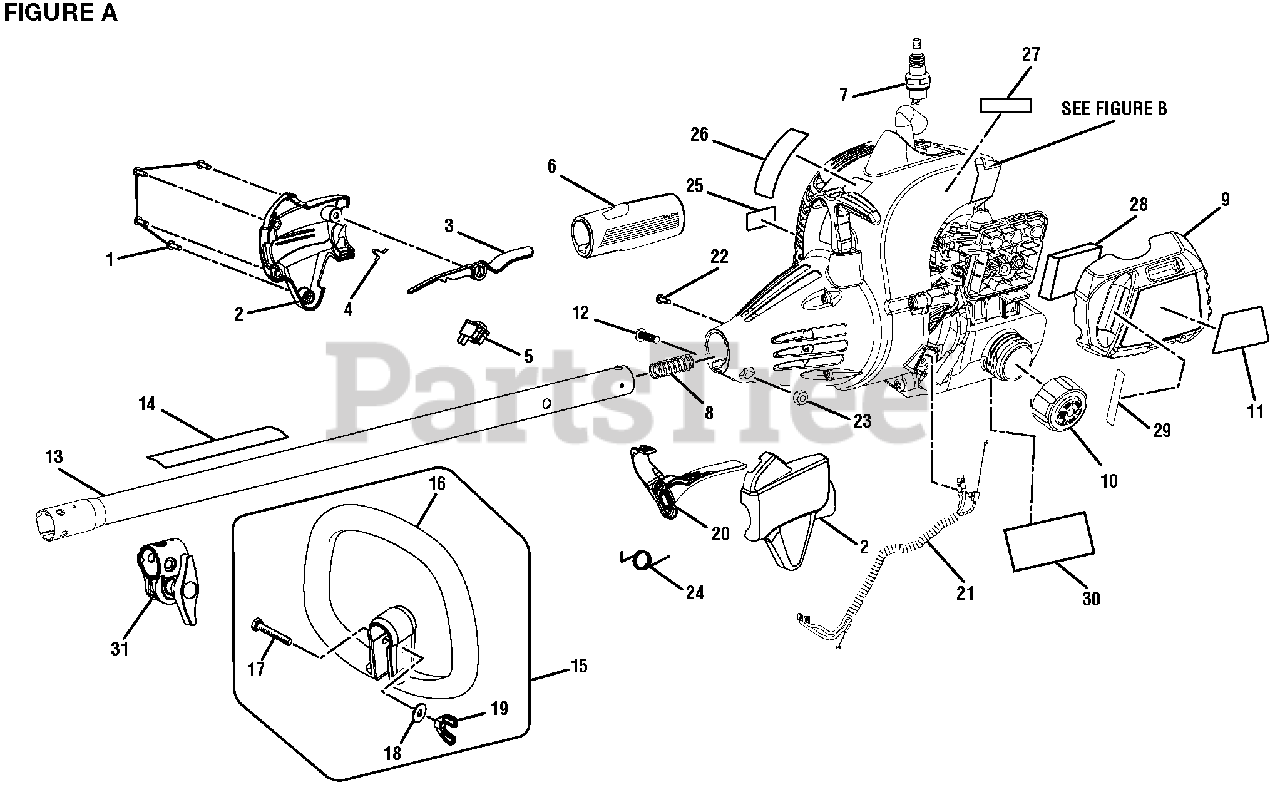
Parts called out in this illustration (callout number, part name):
1	Screw (M4 x 20 mm)
2	Control Handle Assembly
3	Trigger Lock
4	Strap Hanger
5	Switch (Momentary Contact)
6	Rear Handle
7	Spark Plug (Champion RCJ6Y)
8	Compression Spring
9	Air Box Cover
10	Fuel Cap Assembly (1.5 in. Diameter)
12	Bolt (M6 x 20 mm)
13	Upper Boom Assembly
14	Warning Decal
15	Front Handle Assembly
16	Front Handle
17	Bolt (1/4-20 x 40 mm)
19	Wing Nut (1/4-20)
20	Throttle Trigger
21	Throttle and Lead Assembly
22	Screw (M4 x 8 mm, T20 Torx Hd.)
23	Hex Nut (M6)
24	Throttle Spring
25	Combustion Warning Label
26	Logo Label
27	Primer Label
28	Air Filter
29	Start Run Label
30	Fuel Tank Warning Label
31	Boom Clamp
